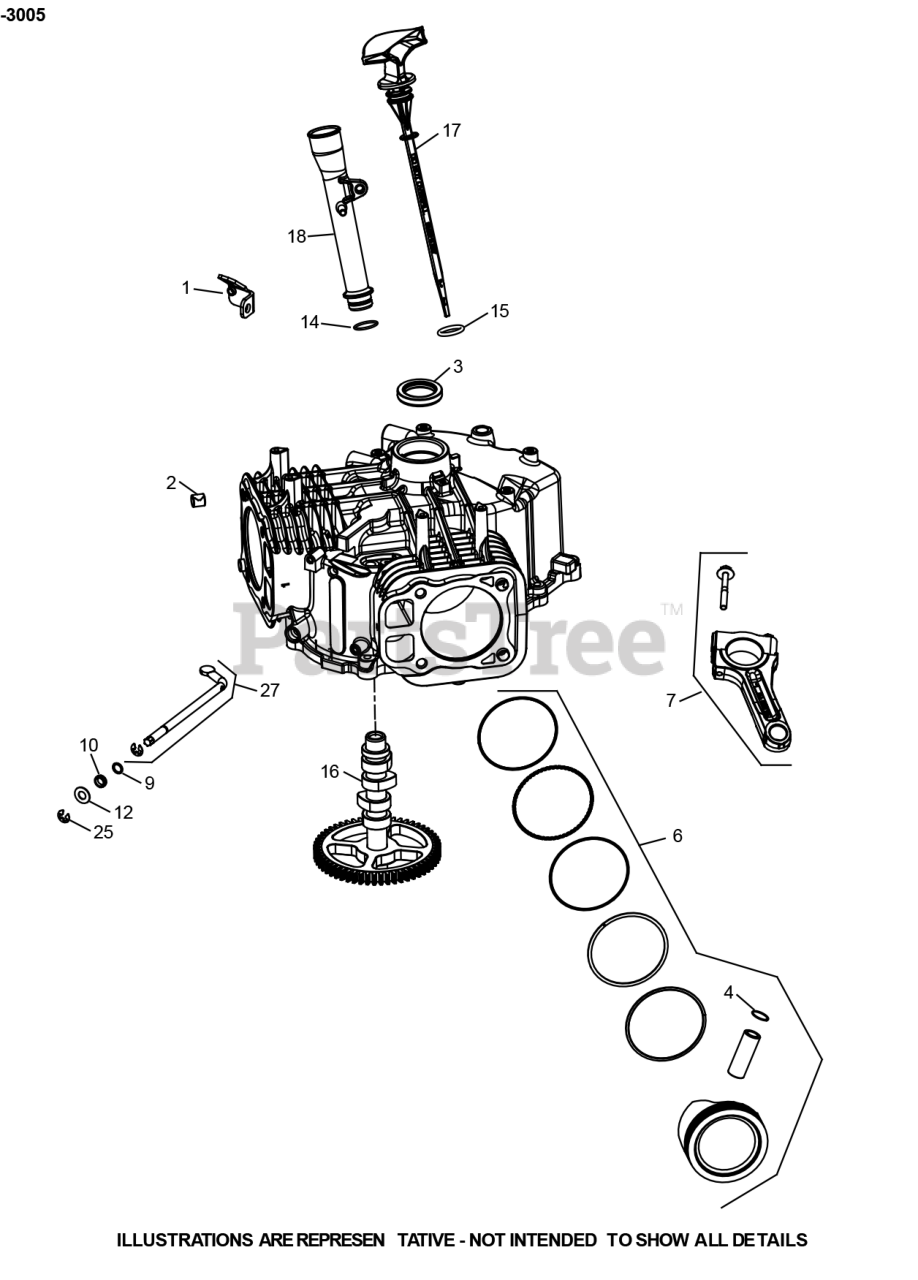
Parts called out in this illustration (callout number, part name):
1	BRACKET-OIL FILL TUBE
2	PIN-SPLIT DOWEL
4	RETAINER-PISTON
6	PISTON KIT (STD)
7	CONNECTING ROD ASSEMBLY
9	WASHER-1/4 FLAT
12	WASHER-9MM FLAT
15	O-RING DIPSTICK
16	CAMSHAFT ASSEMBLY
18	DIPSTICK TUBE
25	GOVERNOR SHAFT RETAINER CLIP
27	CROSS CARBURETOR SHAFT KIT
